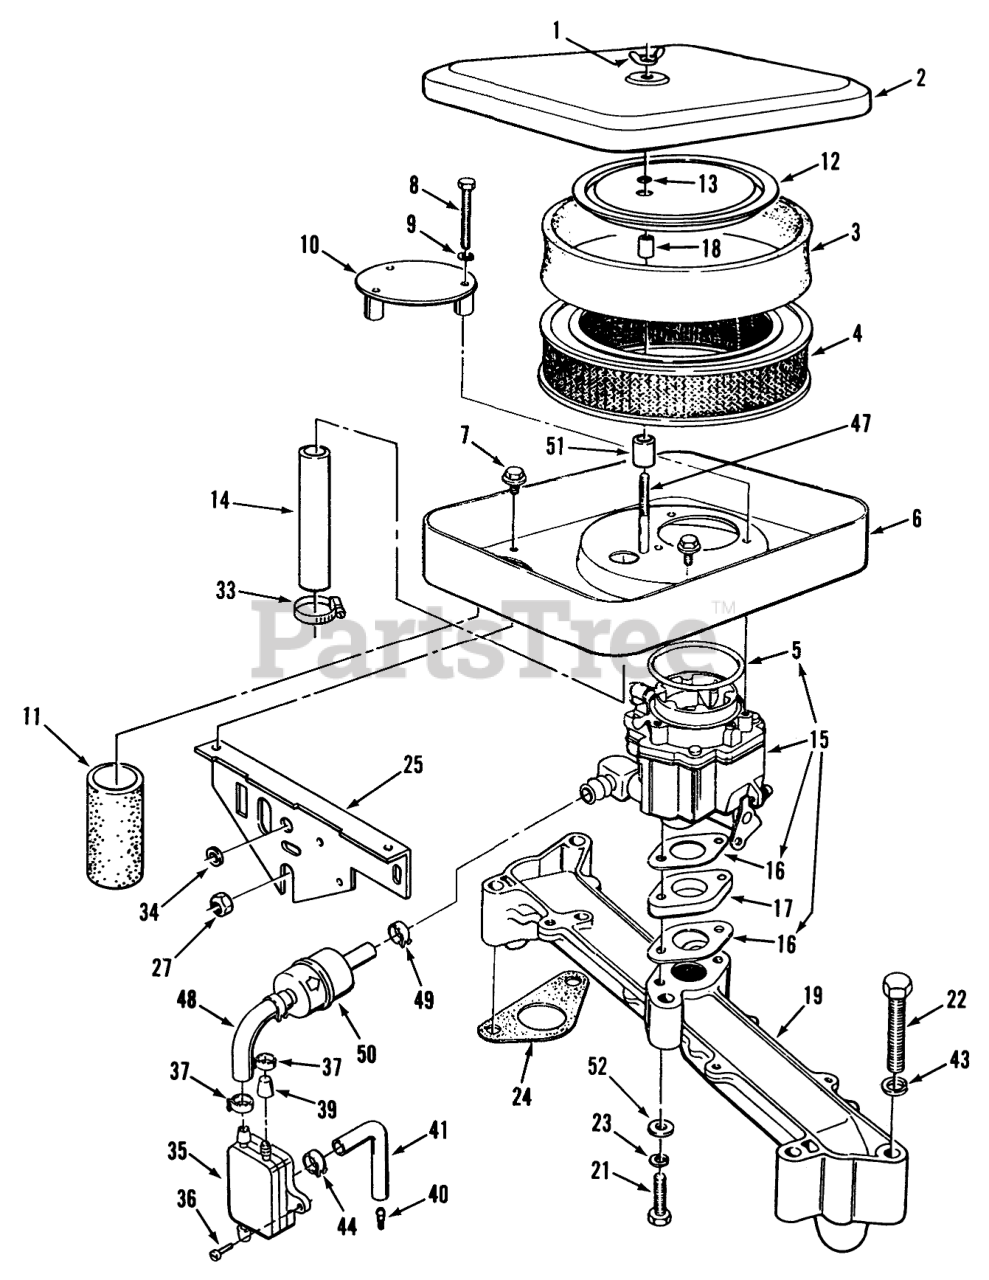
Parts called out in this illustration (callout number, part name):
1	Nut-Wing
2	Air Cleaner Cover
3	Air Cleaner Foam Element
4	Air Cleaner Element
5	"O" Ring
6	AIR CLEANER HOUSING
7	Bolt
8	Screw Hex Hd. #10-32 x 1-1/2
9	Flat Washer #10
10	Air Deflector Plate
11	AIR INTAKE TUBE
12	Element Cover
13	Hex Nut 1/4-20
14	Crankcase Breather Tube
15	Carburetor Complete-See Section 9-8 for complete carburetor breakdown (Includes mounting gasket)
16	Gasket
17	CARBURETOR ADAPTER
18	Spacer
19	Intake Manifold
21	Bolt
22	Hex Hd. Cap Screw 3/8-16 x 3
23	Nut-M8
24	Manifold to Block Gasket
25	Air Cleaner Support
27	Nut
33	Clamp .44" Dia.
34	Grommet
35	Fuel Pump (Includes Hose Clamp and Fuel Cap)
36	Screw
37	Clamp
39	Cap
40	Hose Connector
41	Hose
43	Lockwasher 3/8
44	Clamp
47	Air Cleaner Stud 520-HC Only
48	Hose
49	Clamp
50	Filter-Fuel
51	Spacer
52	Washer
